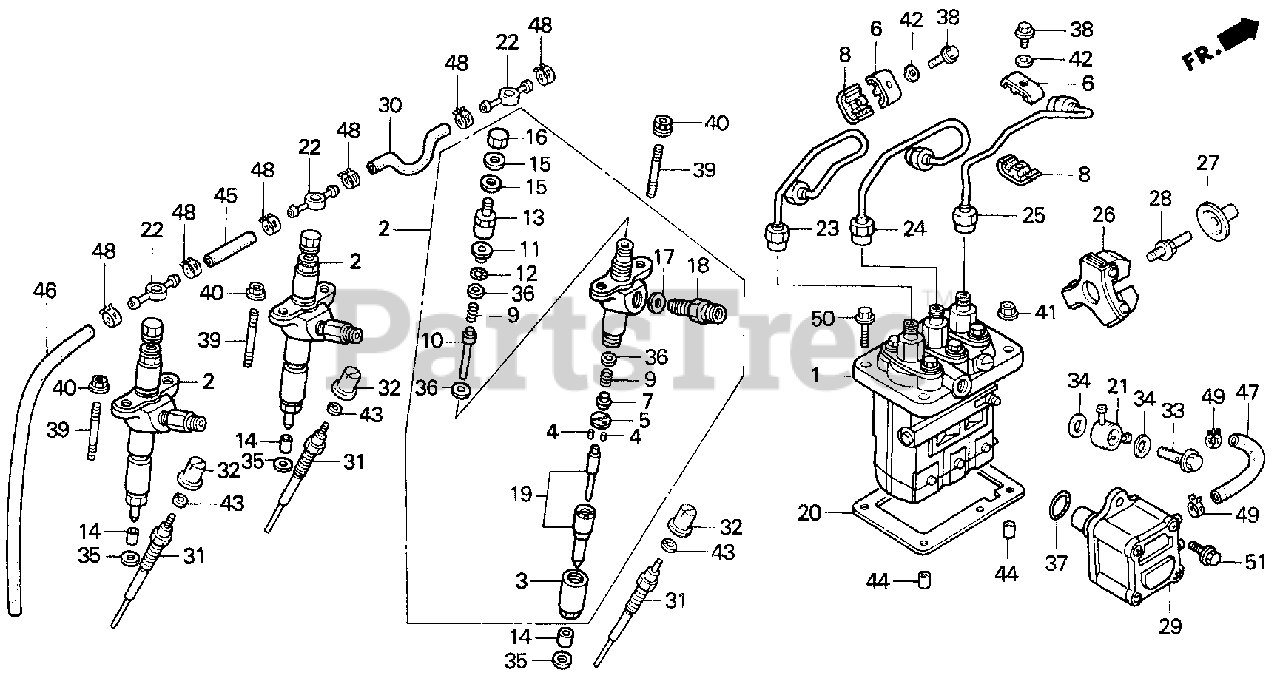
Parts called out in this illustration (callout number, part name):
1	PUMP ASSY., FUEL INJECTION
2	NOZZLE & HOLDER ASSY.
3	NUT, RETAINING
4	PIN (1.78X9.3)
6	HOLDER, FUEL PIPE (A)
7	SEAT, SPRING (A)
8	HOLDER, FUEL PIPE (B)
9	SPRING, NOZZLE
11	SEAT, SPRING (B)
14	COLLAR, NOZZLE
18	CONNECTOR, IN.
20	GASKET A, FUEL INJECTION PUMP (0.5)
20	GASKET B, FUEL INJECTION PUMP (0.3)
20	GASKET C, FUEL INJECTION PUMP (0.1)
21	JOINT, INJECTION PUMP
22	JOINT, FUEL
23	PIPE, FUEL (A)
24	PIPE, FUEL (B)
25	PIPE, FUEL (C)
26	WEIGHT, GOVERNOR
27	SLIDER, GOVERNOR
28	SHAFT, GOVERNOR
29	PUMP ASSY., FUEL
30	TUBE, FUEL
31	PLUG, GLOW
32	NUT, GLOW PLUG
33	BOLT, FUEL JOINT
34	WASHER, FUEL JOINT
35	GASKET, NOZZLE
36	SHIM A (0.50)
36	SHIM B (0.51)
36	SHIM C (0.52)
36	SHIM D (0.53)
36	SHIM E (0.54)
36	SHIM F (0.55)
36	SHIM G (0.56)
36	SHIM H (0.57)
36	SHIM I (0.58)
36	SHIM J (0.59)
36	SHIM K (0.60)
36	SHIM L (0.70)
36	SHIM M (0.80)
36	SHIM N (0.90)
37	O-RING (21.5X2) (ARAI)
38	BOLT, RECESSED (4X18)
39	BOLT 2, STUD (6X32)
40	NUT, FLANGE (6MM)
41	NUT, FLANGE (8MM)
42	WASHER, PLAIN (4MM)
43	WASHER, SPRING (4MM)
44	PIN, DOWEL (6X10)
45	BULK HOSE, FUEL (4.5X3000) (4.5X73)
46	BULK HOSE, FUEL (4.5X3000) (4.5X220)
47	BULK HOSE, FUEL (7.5X3000) (7.3X190)
48	CLIP, TUBE (D8)
49	CLIP, TUBE (D12.5)
50	BOLT, FLANGE (8X22)
51	BOLT, FLANGE (6X18)
